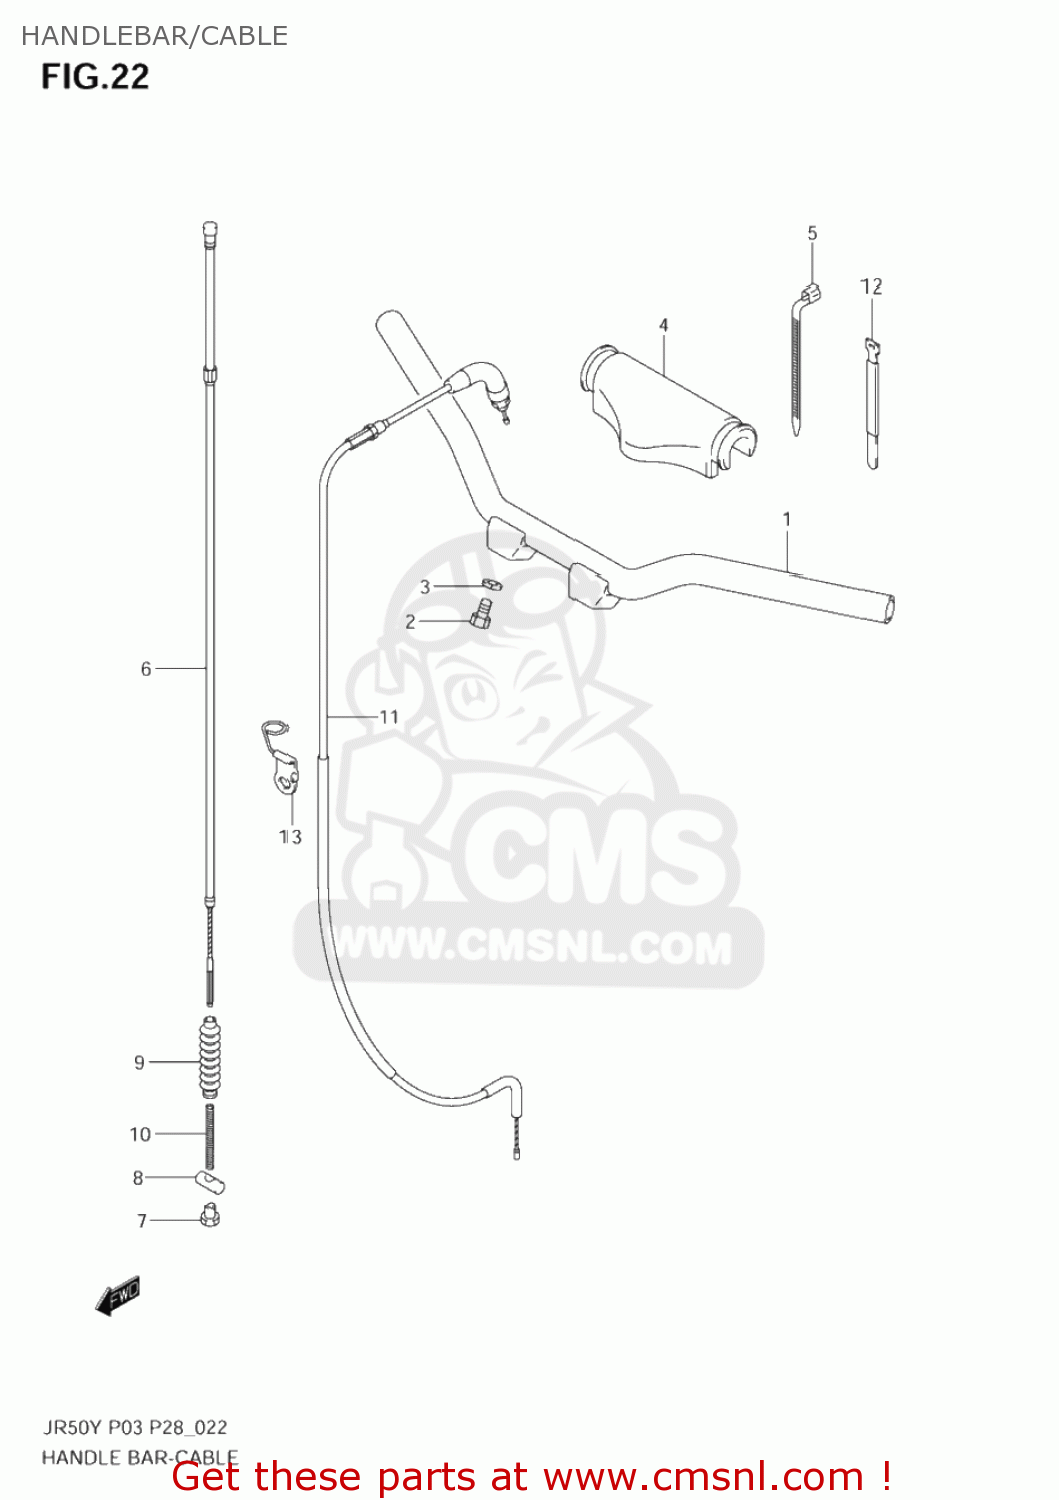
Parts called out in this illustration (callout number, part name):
1	HANDLEBAR
2	BOLT
3	LOCK WASHER
4	COVER,HANDLE
5	CLAMP(L:125)
6	CABLE,FR BRAKE
7	NUT
8	PIN,10X19
9	SEAL,DUST(7X16X75)
10	SPRING
11	CABLE ASSY,THROTTLE
12	CLAMP
13	GUIDE,CABLE
